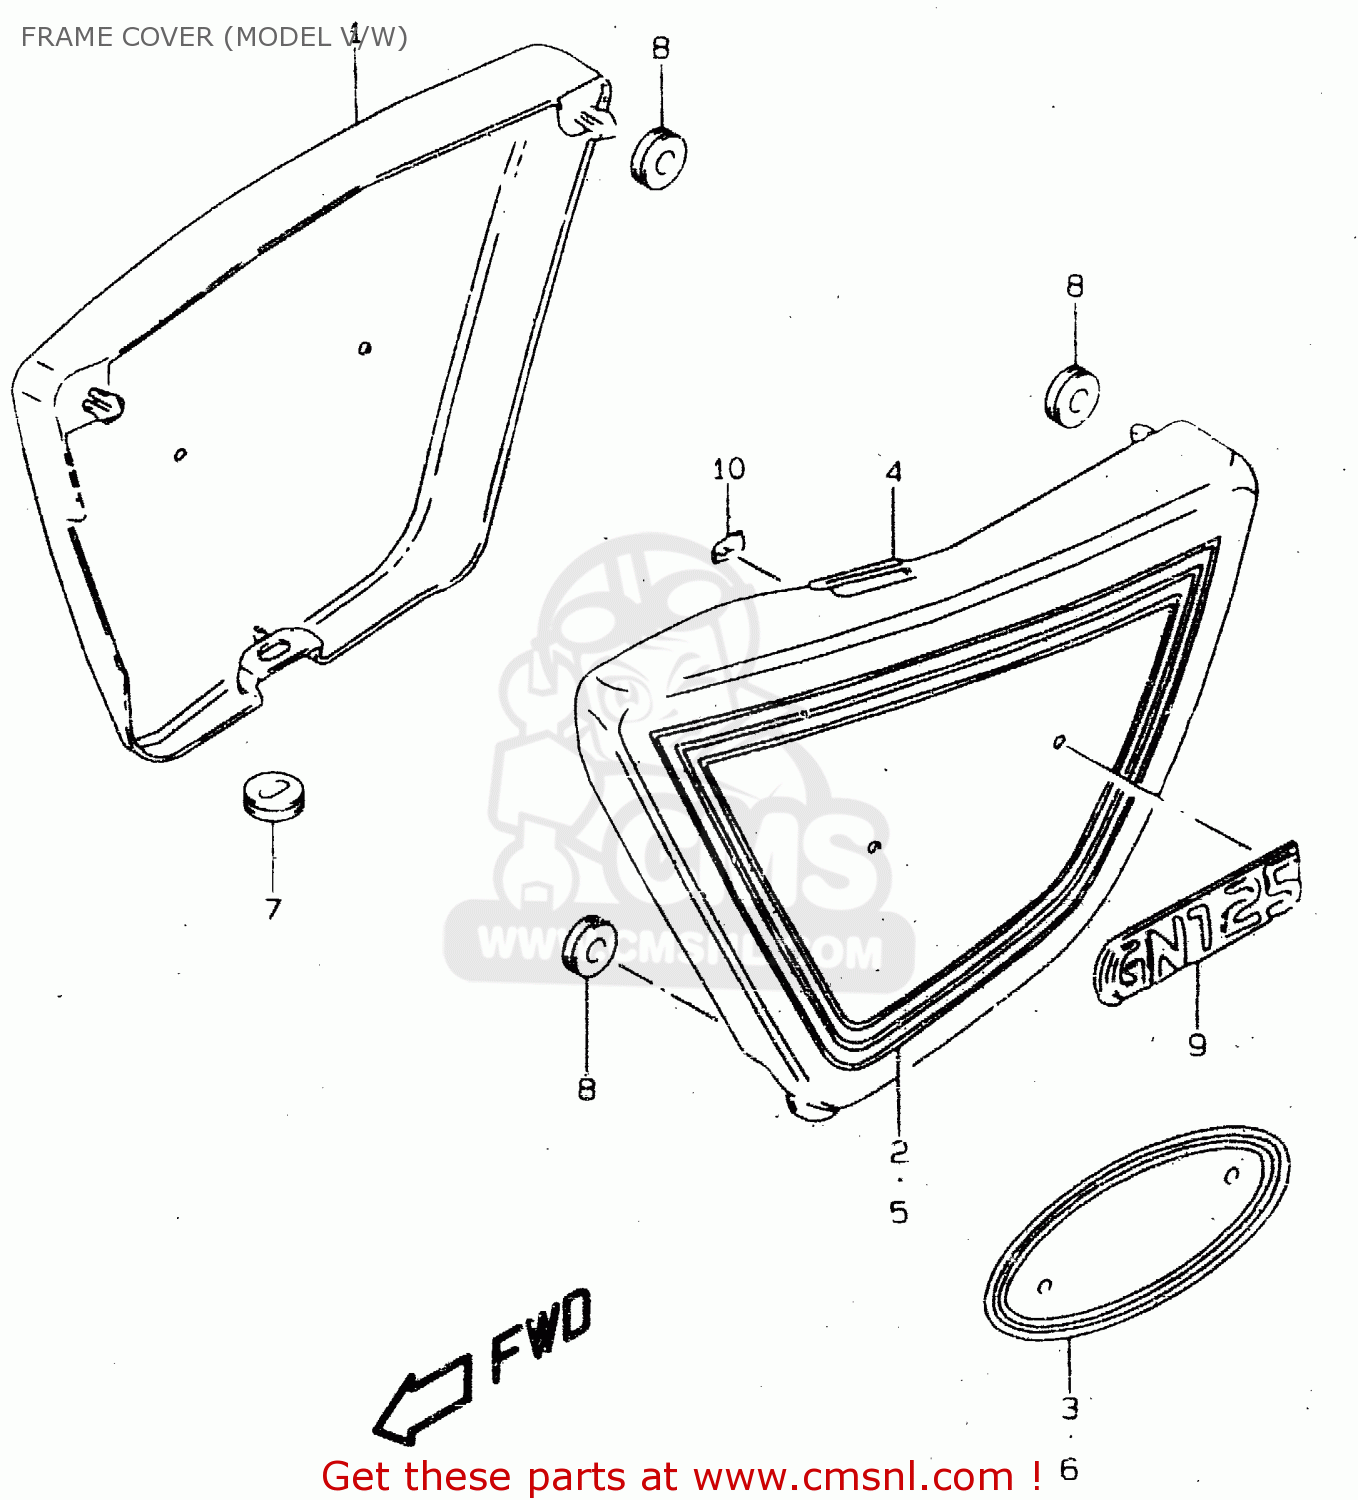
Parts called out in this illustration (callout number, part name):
1	COVER,FRAME,R(RED)
2	TAPE SET,FRAME COVER,R
3	TAPE,FRAME COVER
4	COVER,FRAME,L
5	TAPE SET,FRAME COVER,L
6	TAPE,FRAME COVER
7	CUSHION
8	CUSHION
9	EMBLEM,FRAME COVER
10	NUT
